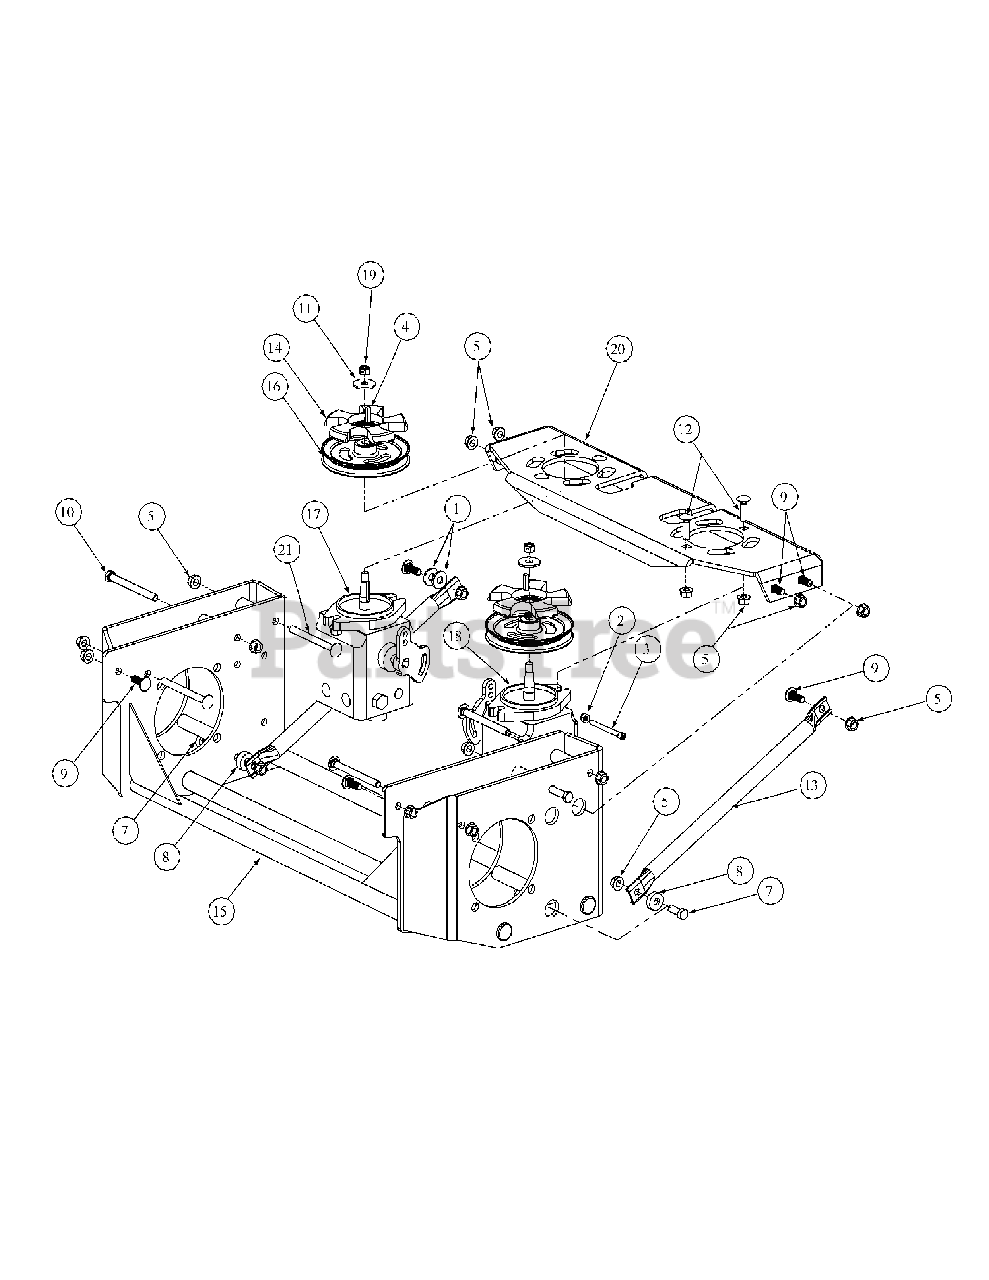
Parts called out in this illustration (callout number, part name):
1	Washer lock 3/8 zinc
2	Lock Nut, Nylon Insert, 1/4-20
3	Socket Head Cap Screw, 1/4-20 x 2-1/2
4	Key, 3/16" x 7/8"
5	Flange Lock Hex Nut, 3/8-16
7	Hex Cap Screw, 3/8 -16 x 1.25
8	Spacer, .406 ID x 1.00 OD x .38
9	Carriage Bolt, 3/8-16 x 1
10	Hex Cap Screw, 3/8-16 x 3.75
11	Flat Washer, .411 x 1.25 x .100
12	Carriage Screw, 3/8-16 x 1.25
14	Hydro Pulley Fan
15	Hydro Motor Frame Assembly
16	Hydro Pump Pulley
17	Hydro Pump, LH
18	Hydro Pump, RH
19	Hex Nut, 3/8-24
20	Hydro Pump Mount
21	Carriage Bolt, 3/8-16 x 4"
